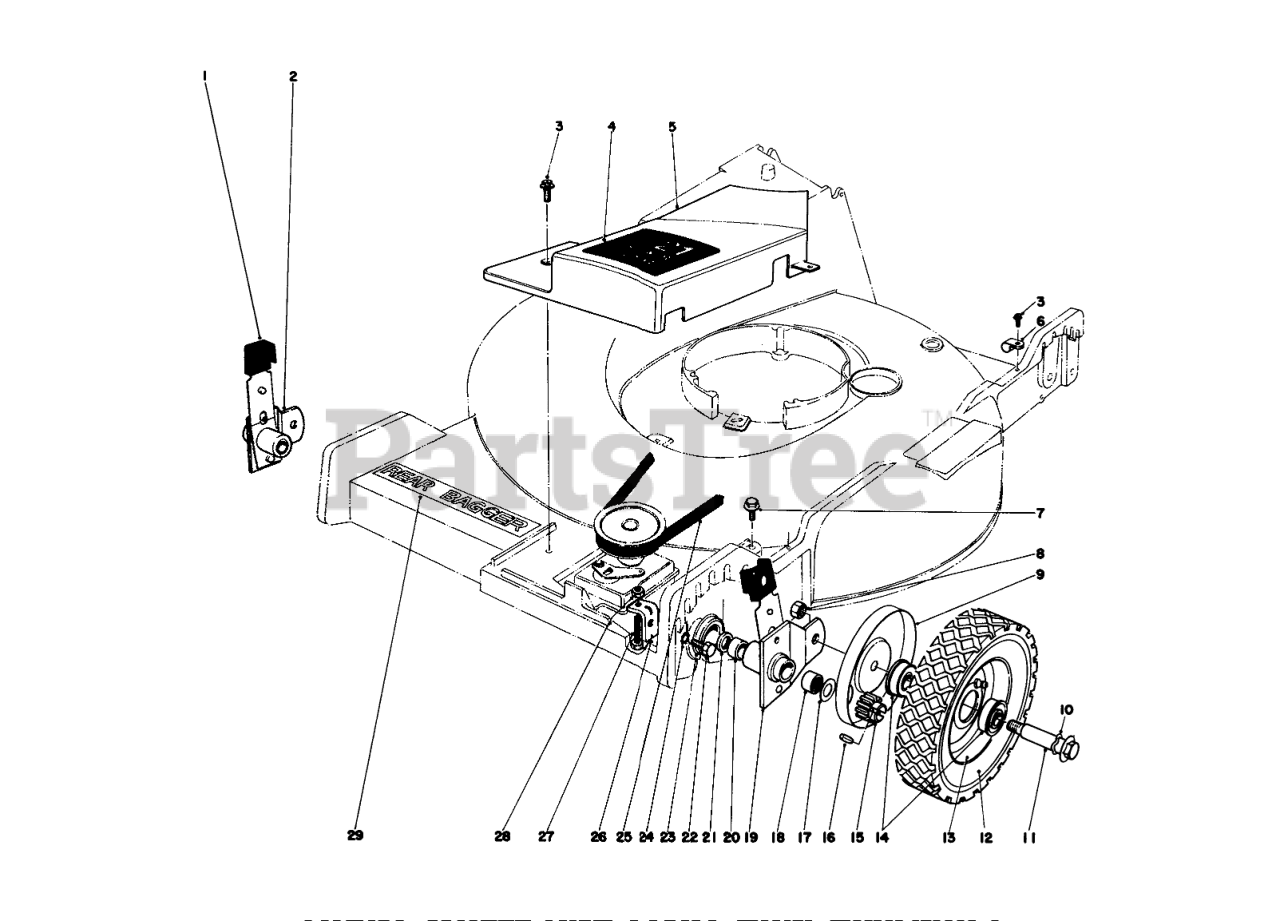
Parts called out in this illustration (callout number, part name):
1	KNOB-ARM
2	Pivot Arm (Incl. Ref. #18 & 20-21)
3	SCREW
4	Decal Belt Cover
5	BELT COVER
6	CLAMP-NYLON
7	SCREW-HWHTF
8	Nut
9	WHEEL COVER
10	SPRING WASHER
11	WHEEL BOLT
13	Wheel & Tire Assembly (Incl. Ref. #12 & 14)
14	BEARING-BALL
15	Pinion
16	PIN-GROOVED
17	WASHER-THRUST
18	Needle Baring
19	Pivot Arm (Incl. Ref. #18 & 20-21)
20	Bushing
21	Seal
22	SCREW-HH
23	END CAP
24	WASHER-LOCK
25	V-BELT
26	Bracket-Gear Box
27	SCREW
28	NUT-LOCK
29	DECK DECAL
